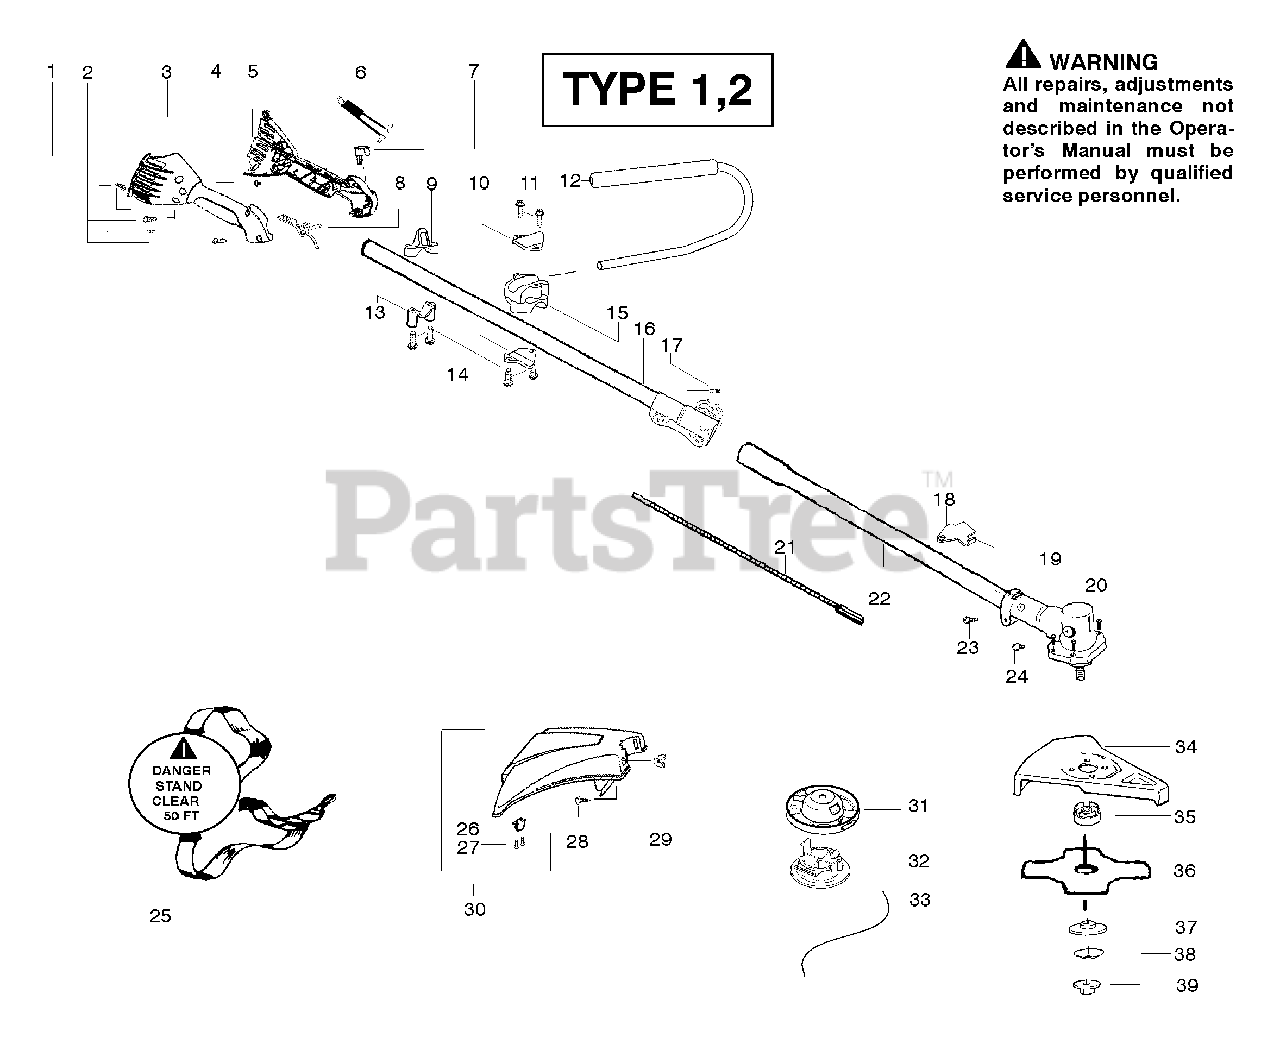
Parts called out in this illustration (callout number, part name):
1	Screw-alignment
3	Hsg.-Throttle-right
4	Screw-Cable Retention
5	Hsg.-Throttle-left
6	Assy-Wire
7	Kit-Switch
8	Trigger-Throttle
9	Clamp-Harness
10	Clamp-Bracket
12	Assy.-Handlebar
13	Clamp-Harness
15	Clamp-Handlebar
16	Kit-Upper Shaft
18	Bracket-Shield
21	Shaft-Flex
22	Assy-Lower Shaft
25	Shoulder Strap
26	Limiter-Line
29	Wingnut
30	Kit-Shield Assy.
31	Head-Fixed line
32	Cap-Fixed Line
33	Accy-Line
34	Kit-Metal Shield
35	Dust cup
36	Accy.-Weed Blade
38	Washer-Belleville
39	Nut-Flange
